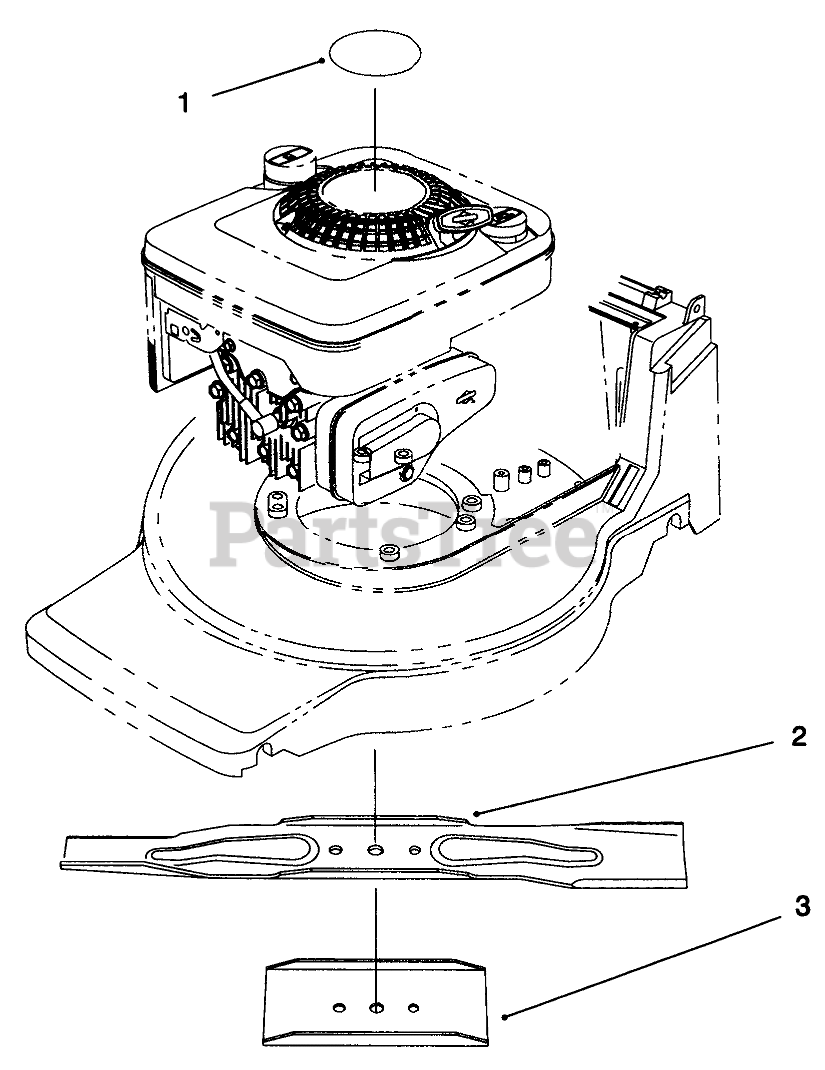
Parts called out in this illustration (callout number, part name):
1	DECAL - ENGINE
2	Blade
3	Stiffener
